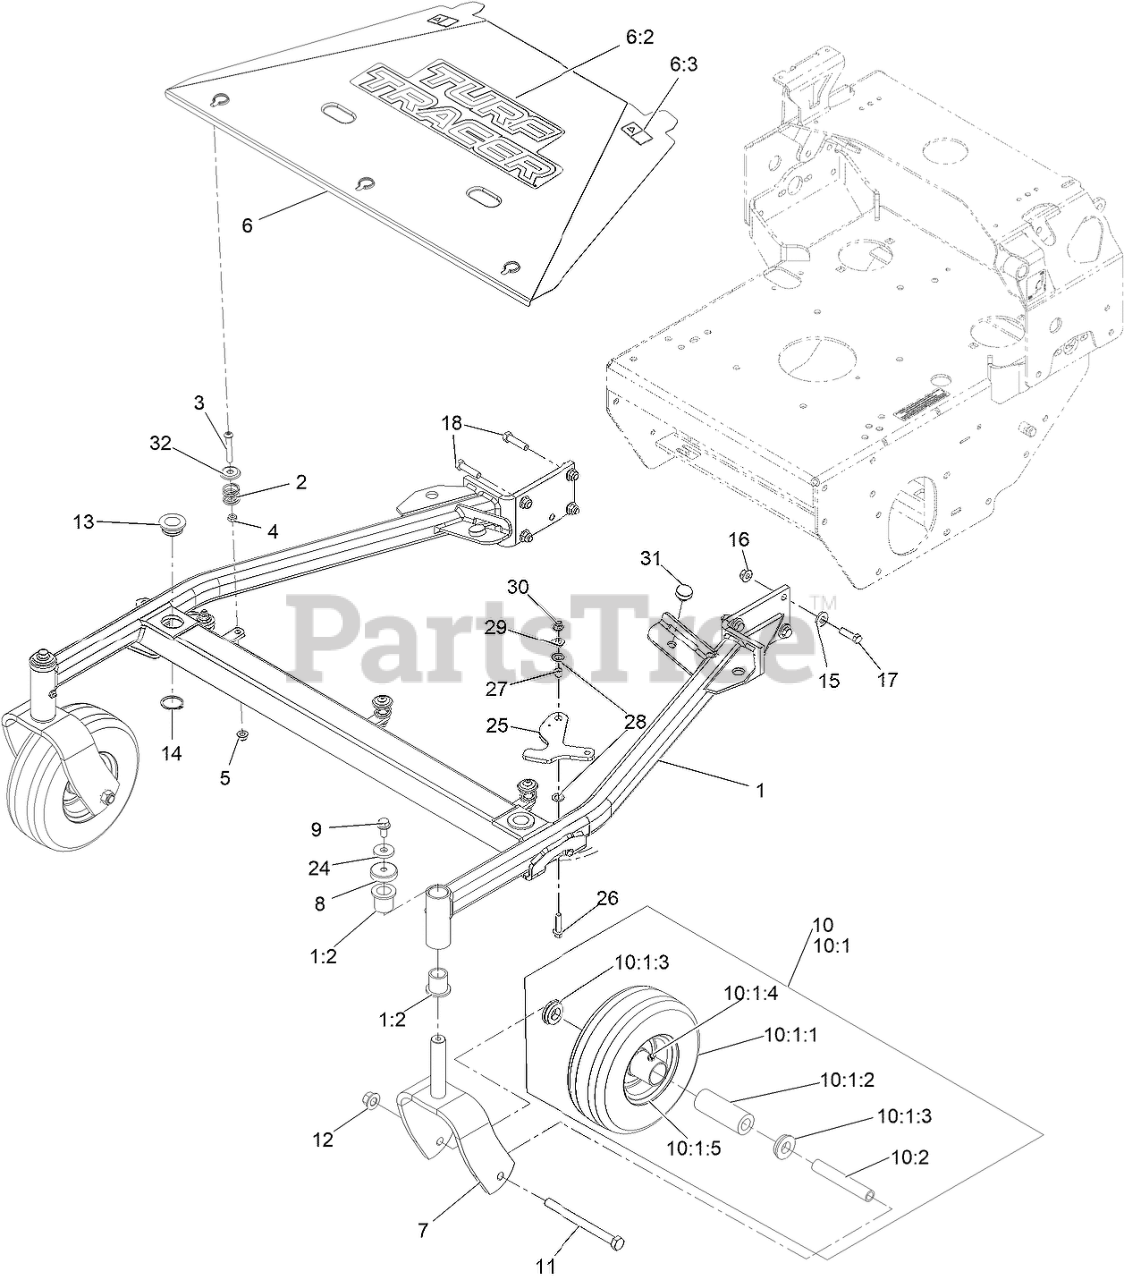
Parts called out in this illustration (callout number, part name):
1	ASM-52" Tts Front Frame
1:2	BEARING-FLANGED
3	SCREW-HSBH
4	NUT-JAM
5	NUT-HF, NI
6	ASM-52" Tts Center Shield
6:2	DECAL-TURF TRACER
6:3	DECAL-WARNING
7	FORK, CASTER
8	CAP, DUST
9	SCREW-HHF
10	KIT, SP CASTER WHEEL REPLACEMENT
10:1	Wheel And Tire ASM
10:1:1	Tire
10:1:2	BEARING
10:1:3	BUSHING
10:1:4	FITTING-GREASE
10:1:5	Wheel
11	SCREW-HH
12	Nut-Lock 1/2-13
13	BUSHING-DECK
14	RING-RETAINING
15	WASHER-BELLEVILLE
16	NUT-HF, NI
17	SCREW-HH
18	SCREW-HH
25	LATCH, DECK HEIGHT
26	Screw-HHF
27	Spacer-Grommet
28	WASHER-CONICAL
29	WASHER-FLAT
30	NUT-HF, NI
31	BUMPER-RUBBER
32	Washer-Cup
